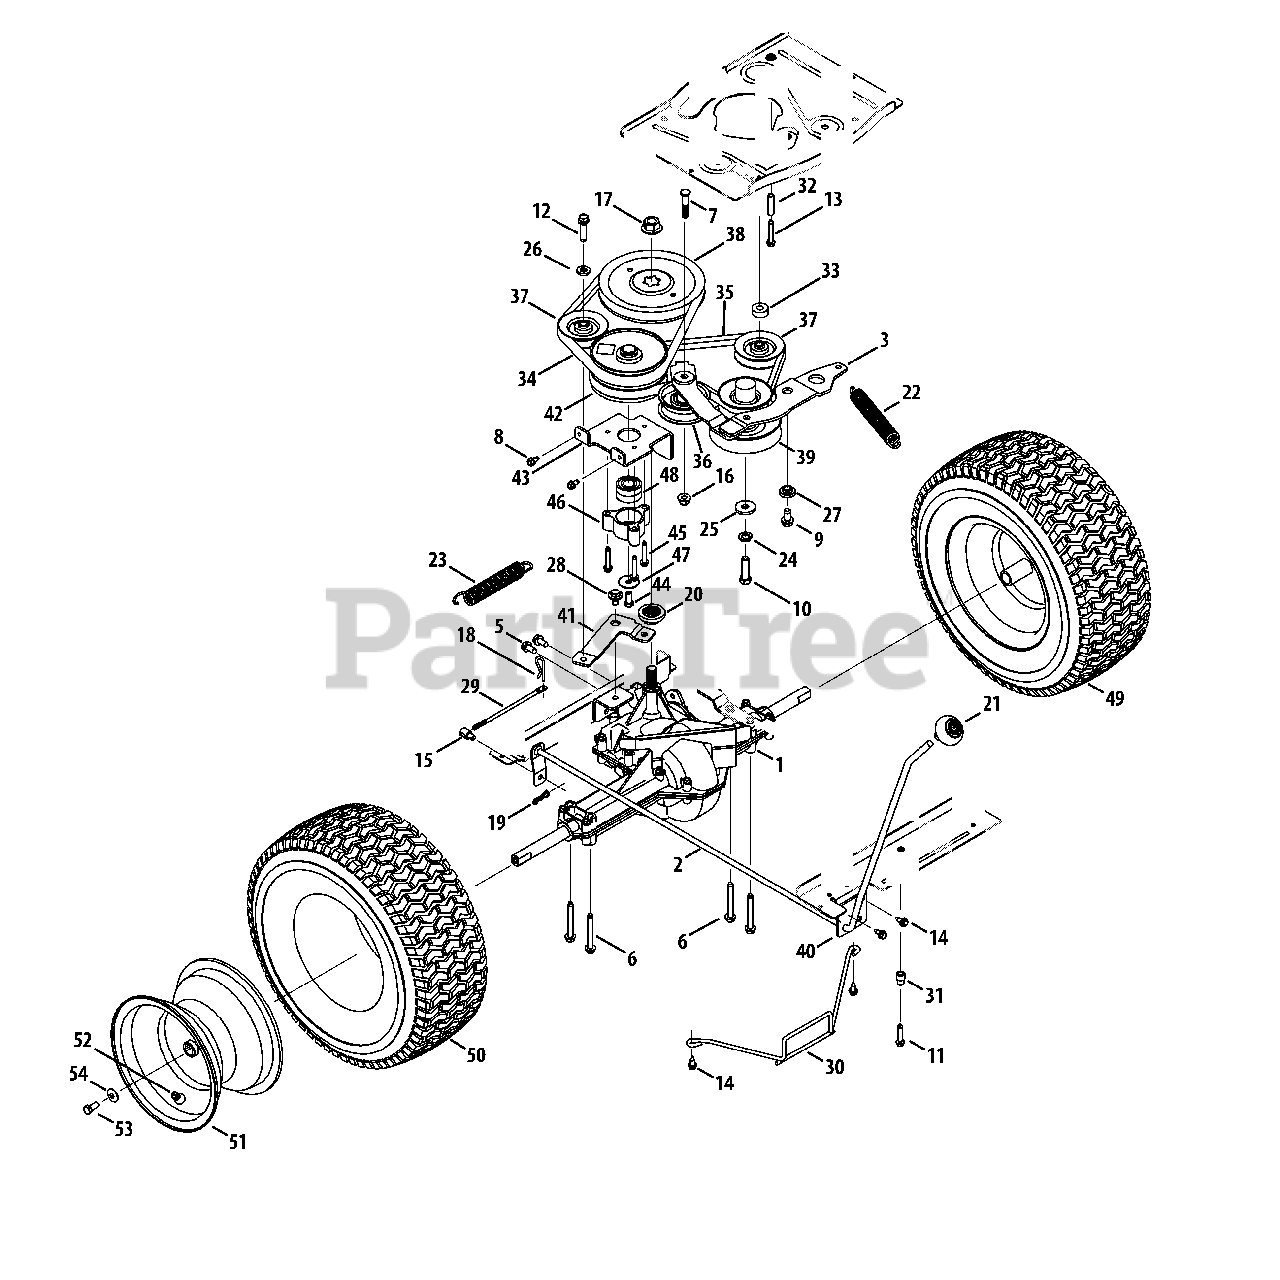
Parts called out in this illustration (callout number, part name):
1	Transmission Assembly
2	Shift Handle Assembly
3	Drive Assembly Idler
5	Tap Screw, 5/16-18, .750
6	Tap Screw, 5/16-18, 2.50
7	Hex Head Scew, 3/8-16, 1.62
8	Tap Scew, 1/4-20, 0.500
9	Tap Screw, 3/8-16, 0.750
10	Hex Head Screw, 7/16-20, 1.50
11	Tap Screw, 1/4-20, 1.250
12	SEMS Tap Screw, 3/8-16, 1.500
13	Tap Screw, 1/4-20, 1.625
14	Tap Screw, 1/4-20 x .625
15	Adjustable Ferrule, 1/4-20 X 1.00
16	Flange Lock Nut, 3/8-16
17	Flange Nut, 9/16-18
18	Internal Cotter Pin, .125 Dia.
19	Bow-Tie Cotter Pin
20	Pulley Hub, 5/8 Spline
21	Shift Knob
22	Extension Spring, .94 Dia. X 6.74 Lg.
23	Extension Spring, .97 OD X 6.18
24	Split Lock Washer, 7/16
25	Flat Washer, .450X1.250X.164
26	Flat Washer, .407X.812X.135
27	Shoulder Spacer, 1.00 X .38 X .38
28	Shoulder Spacer, .560x.165, 5/16-18
29	Shift Rod
30	Deck Belt Keeper, 30"
31	Stepped Spacer, .265 ID X .750
32	Spacer, .260 X .372 X 1.420
33	Spacer, .406 ID X 1.00 OD X .38
34	V-Belt, 5L:35.25
35	V-Belt, 5L:35.28
36	Flat Idler Pulley, 2.75 OD
37	V-Type Idler Pulley, 3.06
38	V-Type Pulley, 6.56
39	Engine Pulley, 4.46 / 3.39
40	Front Support Shift Bracket
41	Rear Idler Arm Bracket
42	Variable Speed Pulley Assembly
43	Variable Bracket Assembly
44	Hex Head Lock Screw, 5/16-24:.750
45	Tap Screw, 1/4-20:1.500
46	Bearing Cup
47	Flat Washer, .330x1.250x.060
48	Ball Bearing, 17 X 40 X 12
49	Complete Wheel Assembly
50	Tire, 16 x 6.5 x 8 Sq. Shldr.
51	Rim Assembly, 8.0 x 5.38
52	Air Valve
53	Hex Head Screw, 5/16-24, 7.50
54	Beveled Washer, .340 x .872 x .060
